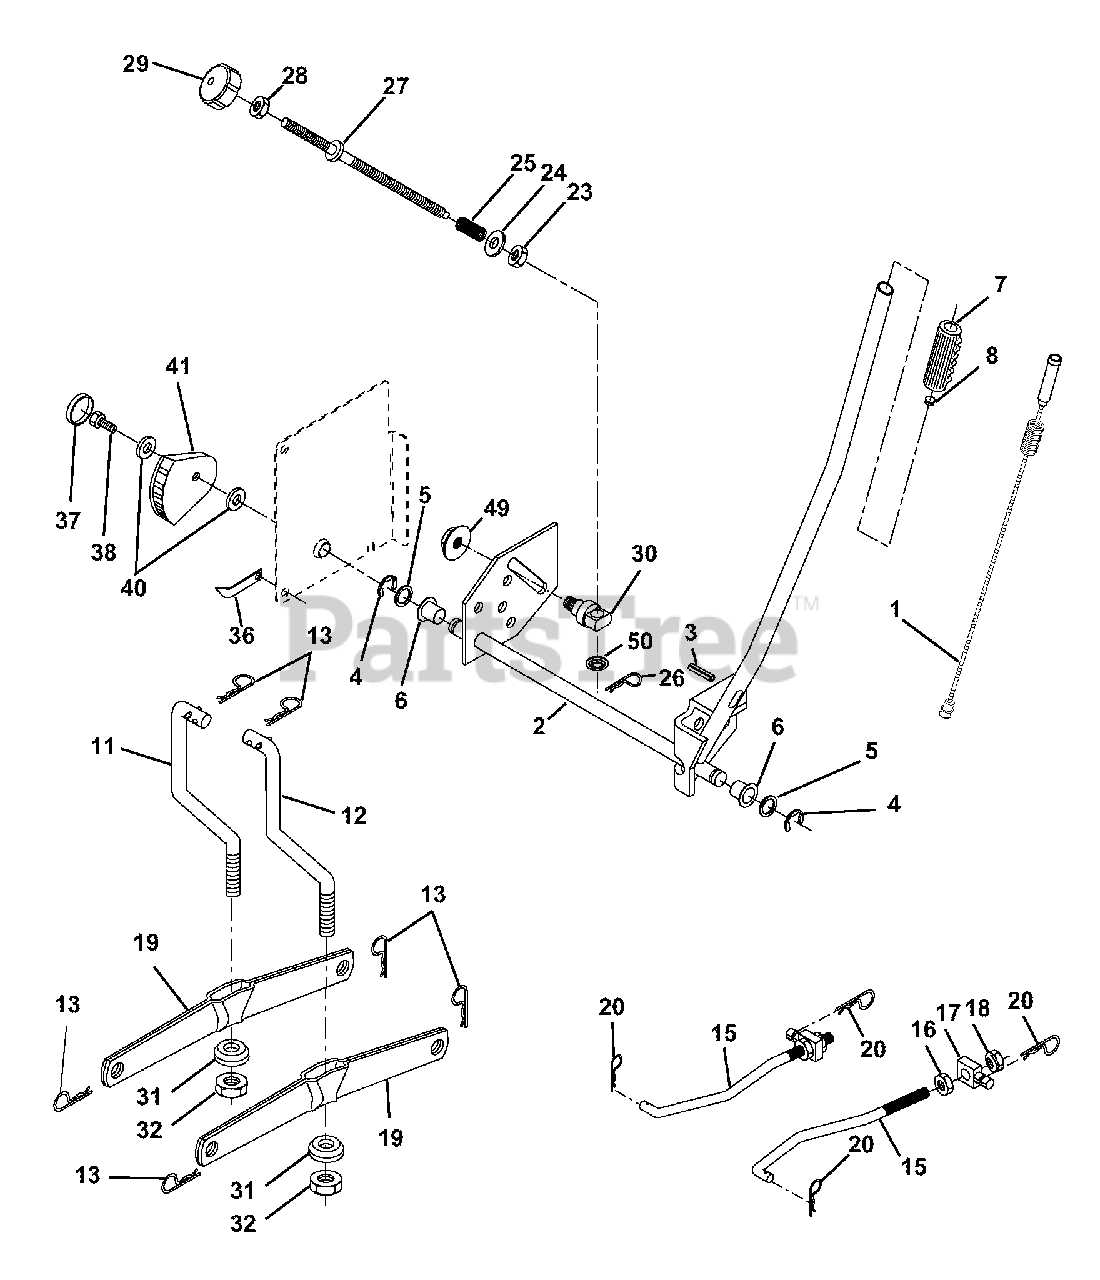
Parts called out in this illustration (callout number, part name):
1	Wire Asm Inner/Sprg W/plunger
2	Shaft Asm Lift RH w/Inf
3	Pin Groove
4	E Ring #5133-62
5	Washer 21/32 X 1 X 21 Ga
6	Bearing Nylon Blk 629 Id
7	Grip Handle
8	Button Plunger
11	Link Lift LH Fixed Length
12	Link Lift RH Fixed Length
13	Retainer Spring
15	Link Front
16	Nut Jam Hex 1/2-13 Unc
17	Trunnion Blk Zinc
18	Nut Lock w/Wsh 1/2-13unc
19	Arm Suspension Rear
20	Retainer Spring
23	Nut Special
24	Washer 13/32 X 5/8 X 16 Ga
25	Spring
26	Retainer Clip
27	Rod Adj Lift
28	Nut Hex Jam 3/8-16 Unc
29	Knob Inf 3/8-16 Unc Blk W/sym
30	Trunnion Infin Height
31	Bearing Pvt Lift
32	Nut Crownlock 3/8 - 24
36	Pointer Height Indicator
37	Plug Hole Blk 1.485/1.515 Dia.
38	Screw 5/16-18 x 1
40	Washer 11/32 x 1-1/2 10 Ga.
41	Indicator Height STLT
49	Nut Hex Flange Lock
50	Nut PUsh Phos & Oil
